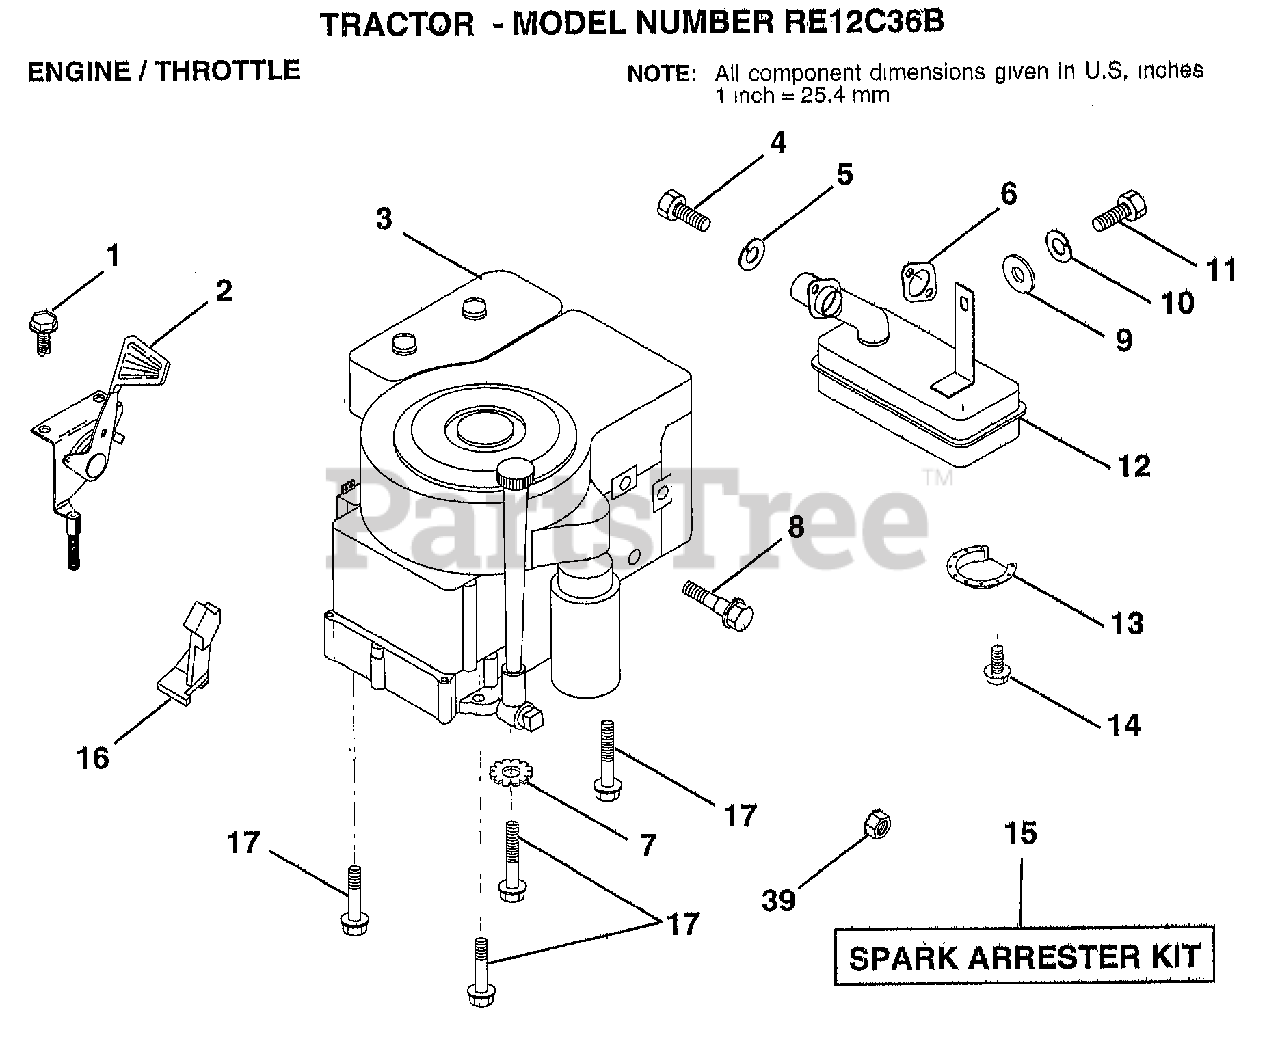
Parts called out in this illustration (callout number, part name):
1	SCREW.1/4-20X1/2
4	SCREW
5	LOCKWASHER
7	LOCKWASHER
8	BOLT T
10	LOCKWASHER
12	MUFFLER
13	DEFLECTOR.222573
16	"STOP,DASH THROTT"
17	SCREW LT
39	NUT
